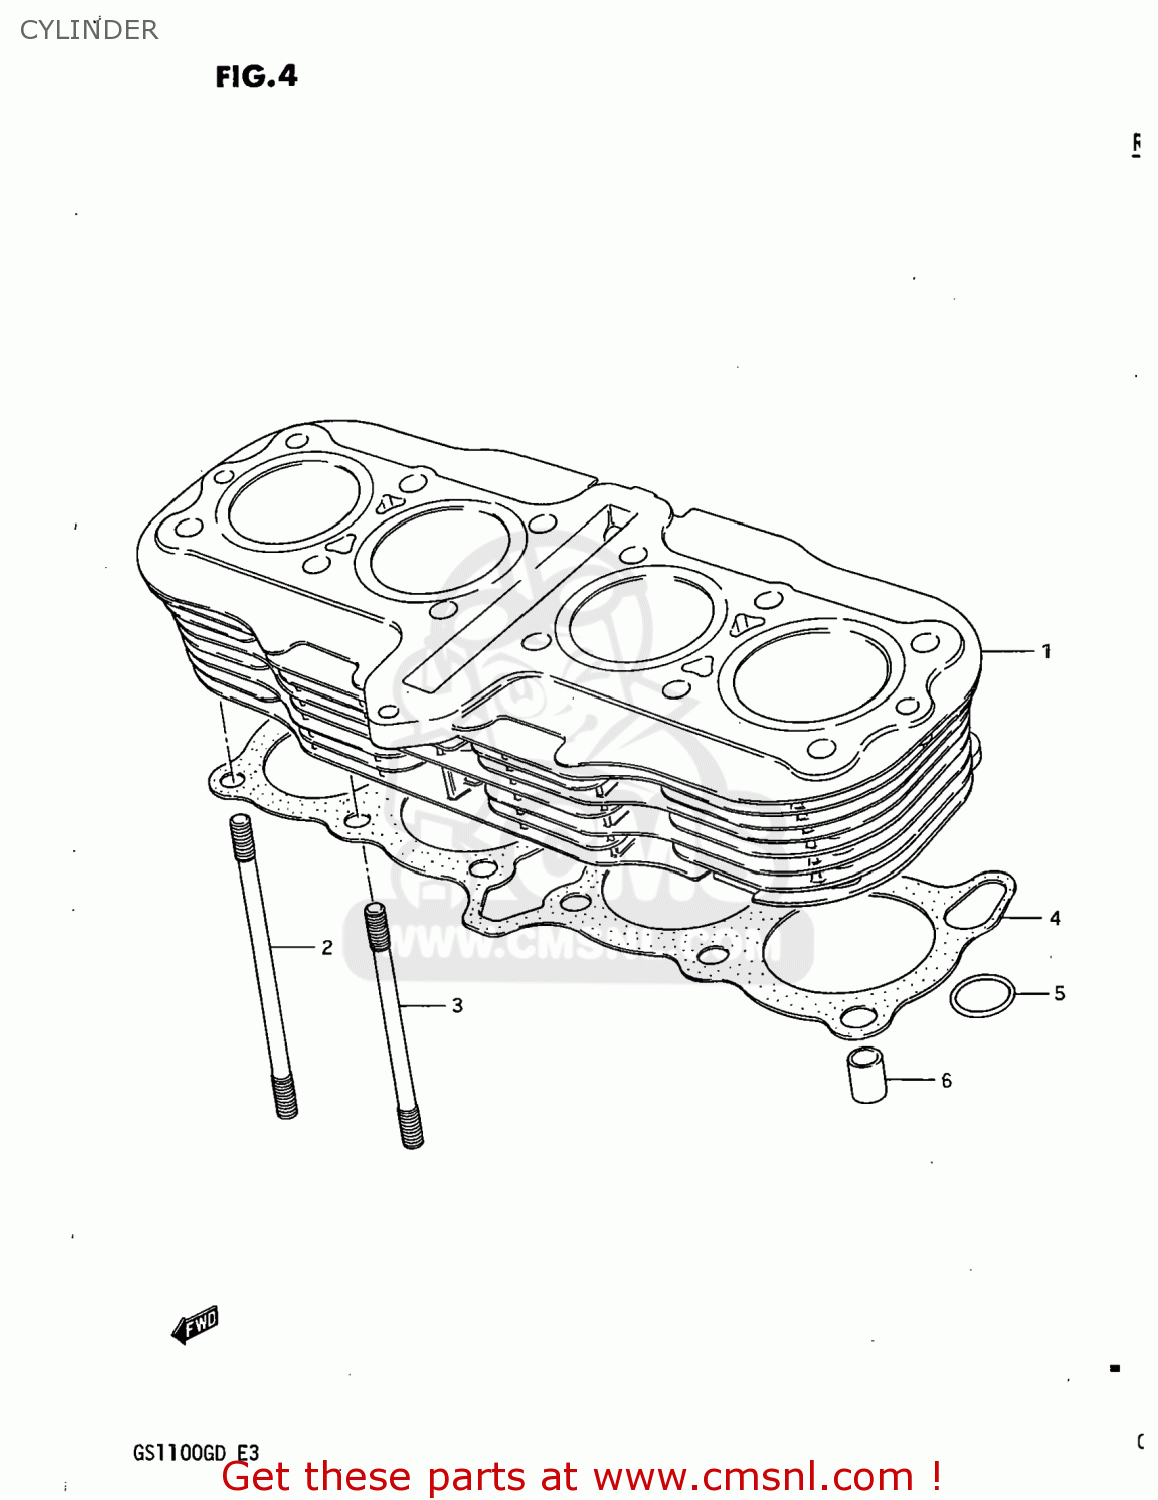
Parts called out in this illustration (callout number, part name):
1	CYLINDER
2	BOLT,STUD
3	STUD
4	GASKET,CYLINDER (MCA)
5	O RING(D:3.5)
6	PIN
